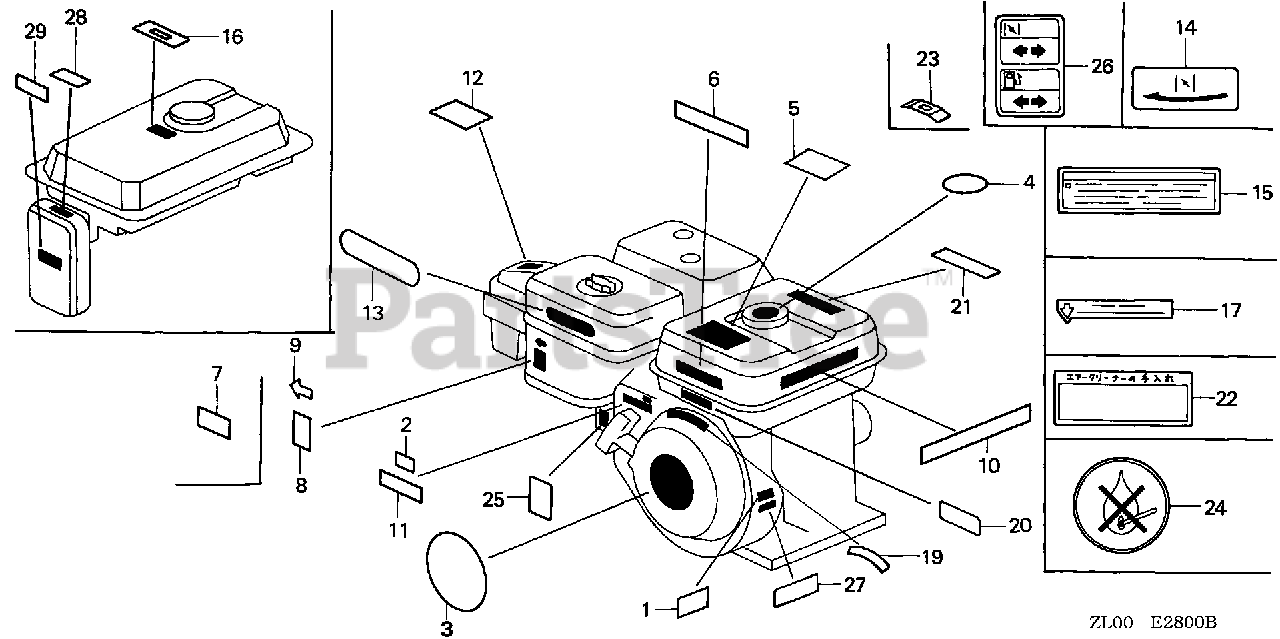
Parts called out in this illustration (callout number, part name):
6	LABEL, CAUTION (ENGLISH, ETC.)
8	MARK, CHOKE
10	MARK, OIL ALERT (GERMAN)
10	MARK, OIL ALERT (FRENCH)
10	MARK, OIL ALERT (ENGLISH)
